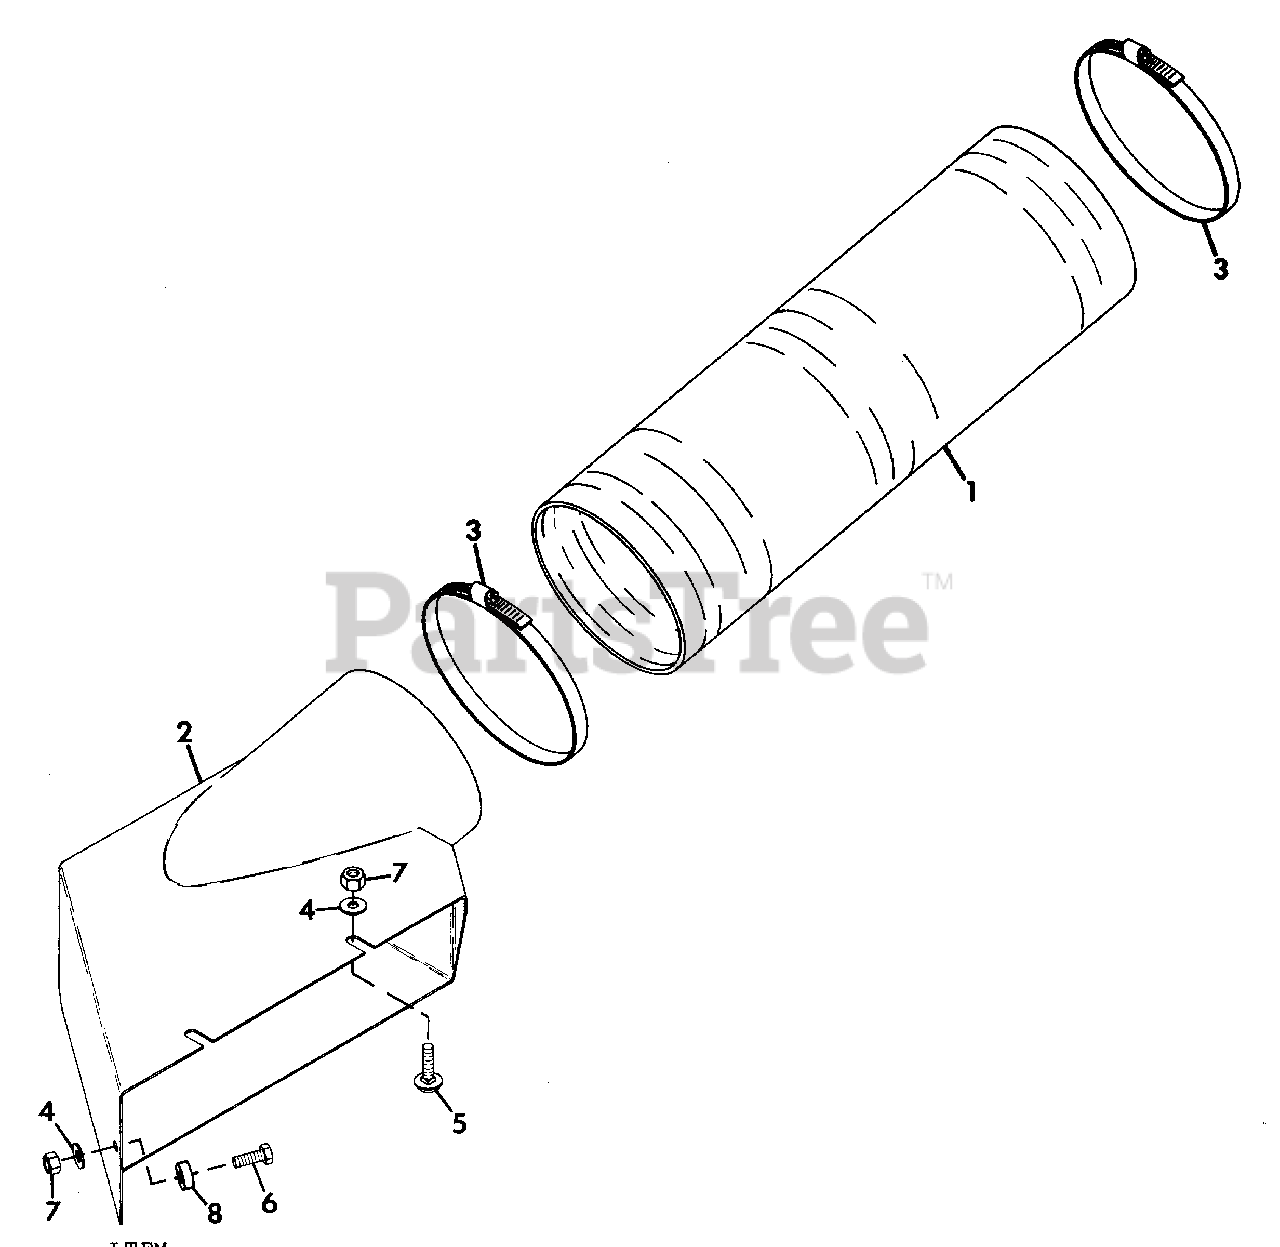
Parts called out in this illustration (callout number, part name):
1	HOSE, MOWER TO BLOWER
2	BOOT, 40"
2	BOOT, 50"
3	CLAMP
4	WASHER, FLAT .406X.812X.065
5	BOLT, CARRIAGE 3/8-16X.75
6	BOLT, HEX 3/8-16X1.00
6	BOLT, HEX 3/8-16X1.25
7	NUT, LOCK 3/8-16
8	BUSHING, REVERSE IDLER
